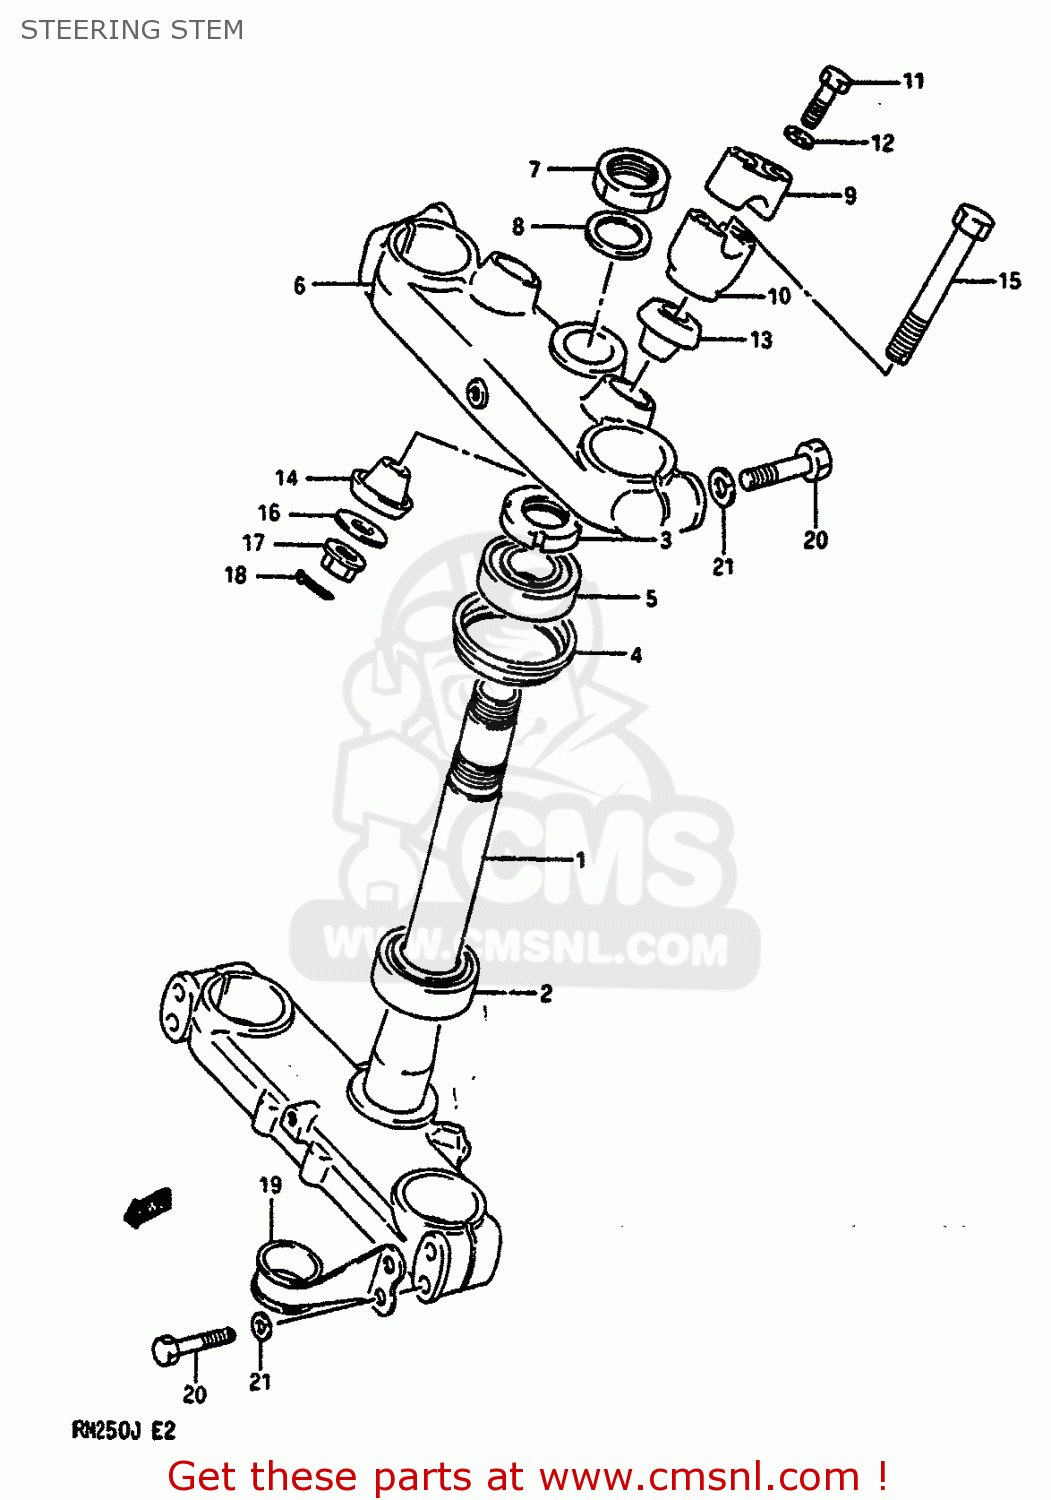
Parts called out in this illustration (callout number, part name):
1	STEM,STEERING
2	BEARING
3	NUT,STEERING STEM
4	SEAL,STEERING UPR DUST
5	TAPER,ROLLER BEARING
6	STEM HEAD,STEERING
7	NUT,STEERING STEM
8	WASHER
9	HOLDER,HANDLEBAR
10	HOLDER,HANDLE LWR
11	BOLT
12	WASHER,LOCK
13	DAMPER,UPR
14	DAMPER,LWR
15	BOLT,HANDLE HOLDER
16	WASHER,HANDLEBAR HOLDER
17	NUT
18	COTTER PIN
19	CLIP
20	BOLT 8X40
21	WASHER,LOCK
